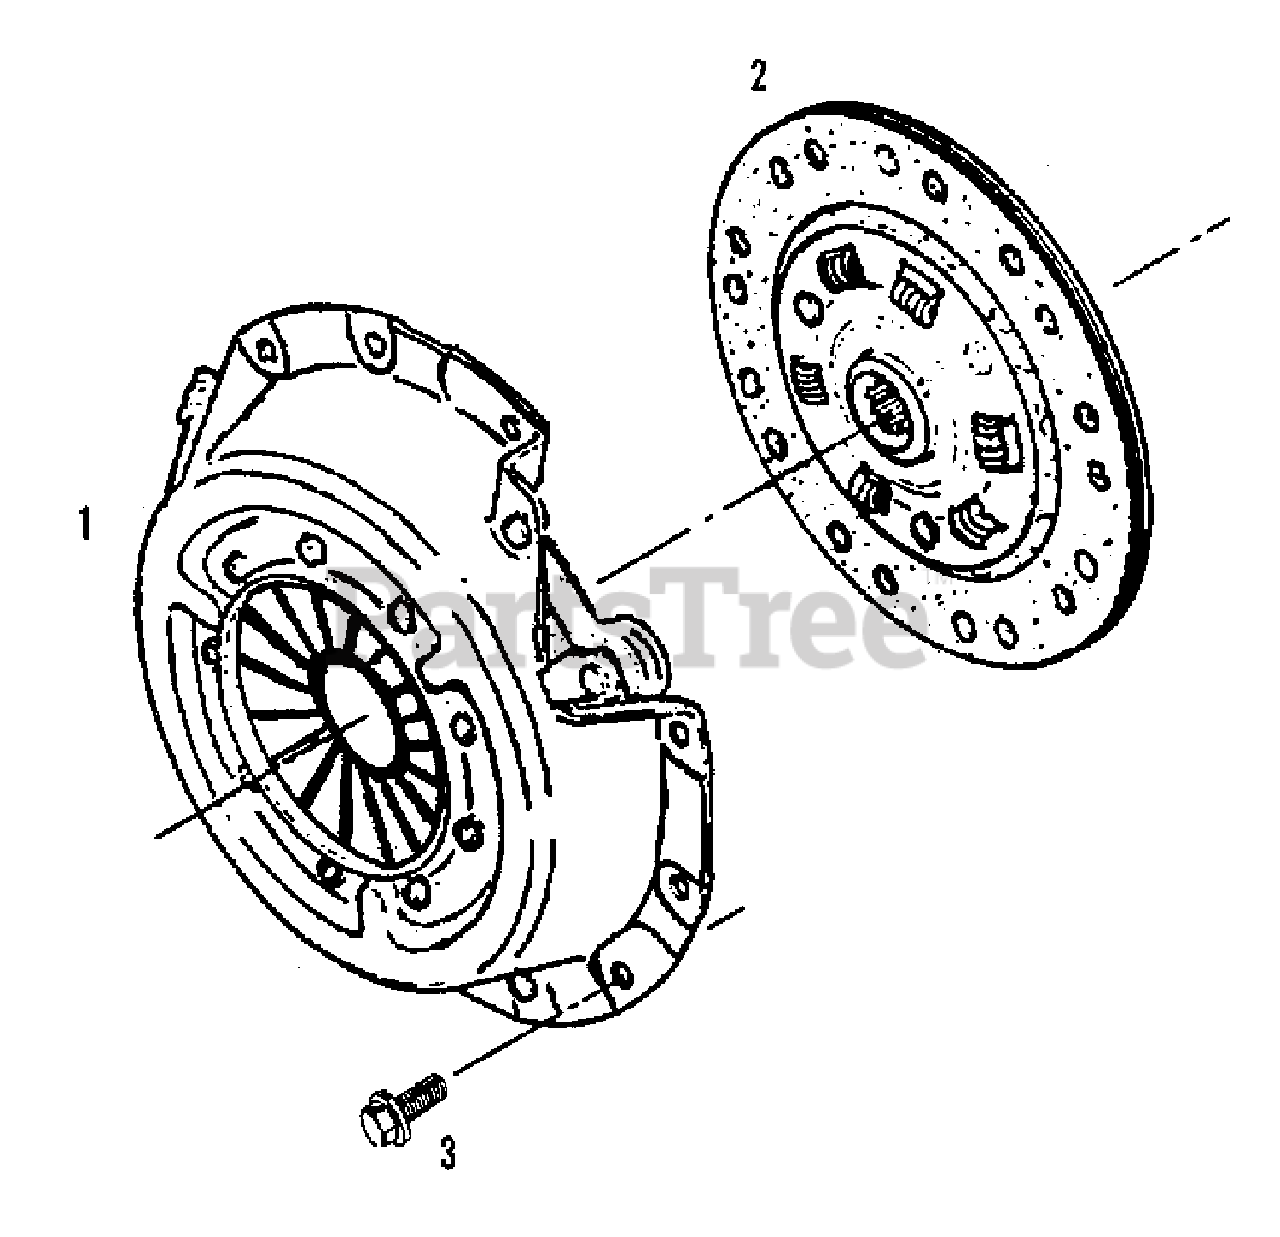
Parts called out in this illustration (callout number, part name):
1	PLATE ASSEMBLY, pressure
2	DISC ASSEMBLY, driven
3	CAPSCREW, w/lockwasher, M8 x 18
